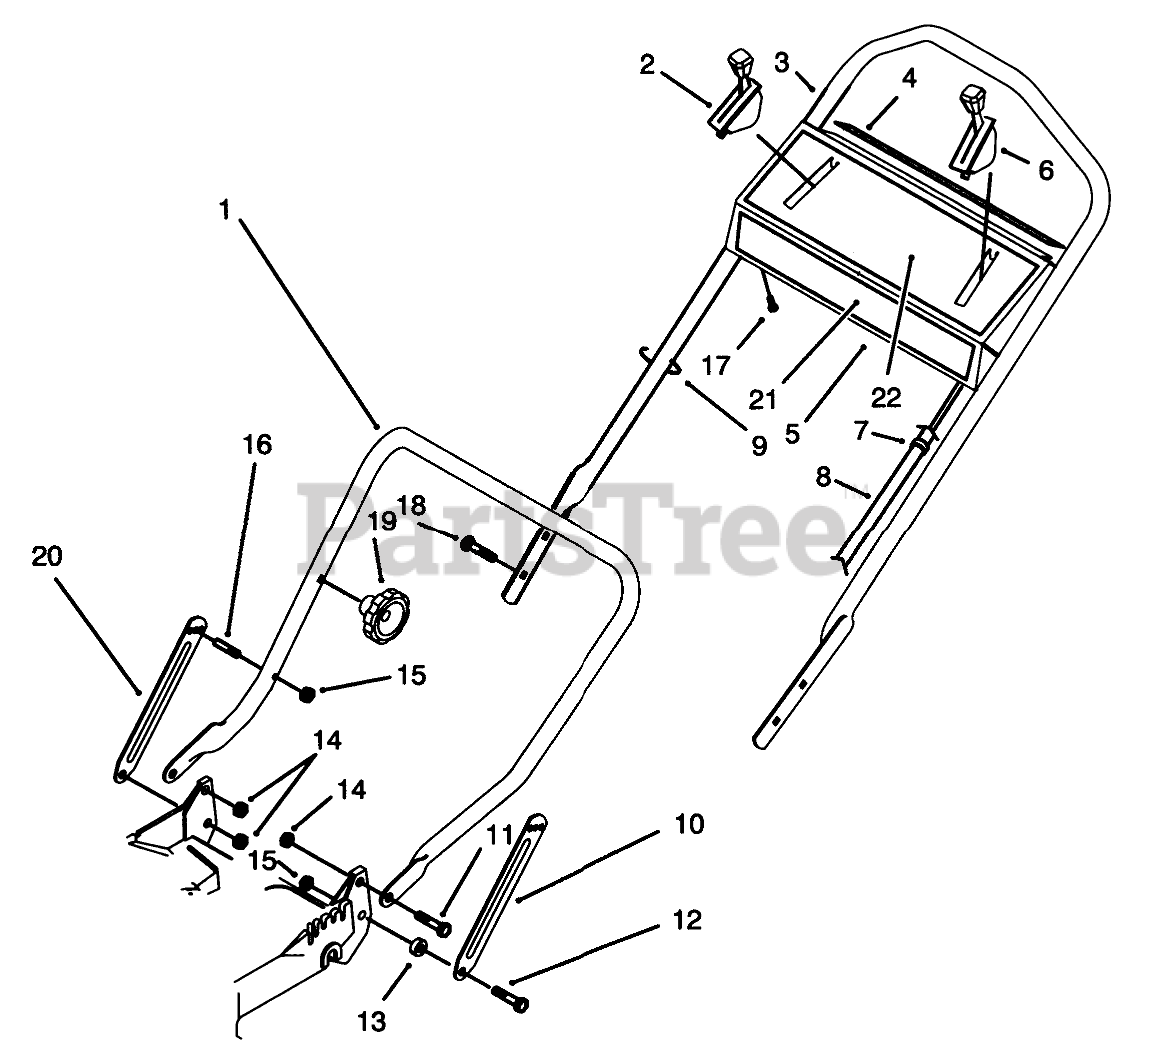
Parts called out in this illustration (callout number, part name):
1	LOWER HANDLE ASM
2	Control-Ground Speed
3	UPPER HANDLE, PVC DIP
4	DECAL - PANEL, REAR
5	Panel-Control (Incl. Ref. #4 & 22)
6	THROTTLE CONTROL
7	FITTING-RING
8	CONTROL CABLE COVER
9	TIE-CABLE
10	LH HANDLE LATCH
11	SCREW-SHOULDER
12	SCREW-SHOULDER
13	SPACER
14	NUT-LOCK, NI
15	NUT-LOCK, NI
16	HANDLE PIN
17	10-16X1/2 SHWH SCREW
18	5/16-18 X 2 HNDLE SCREW
20	RH HANDLE LATCH
21	DECAL - TORO
22	DECAL - INSTRUCTION
